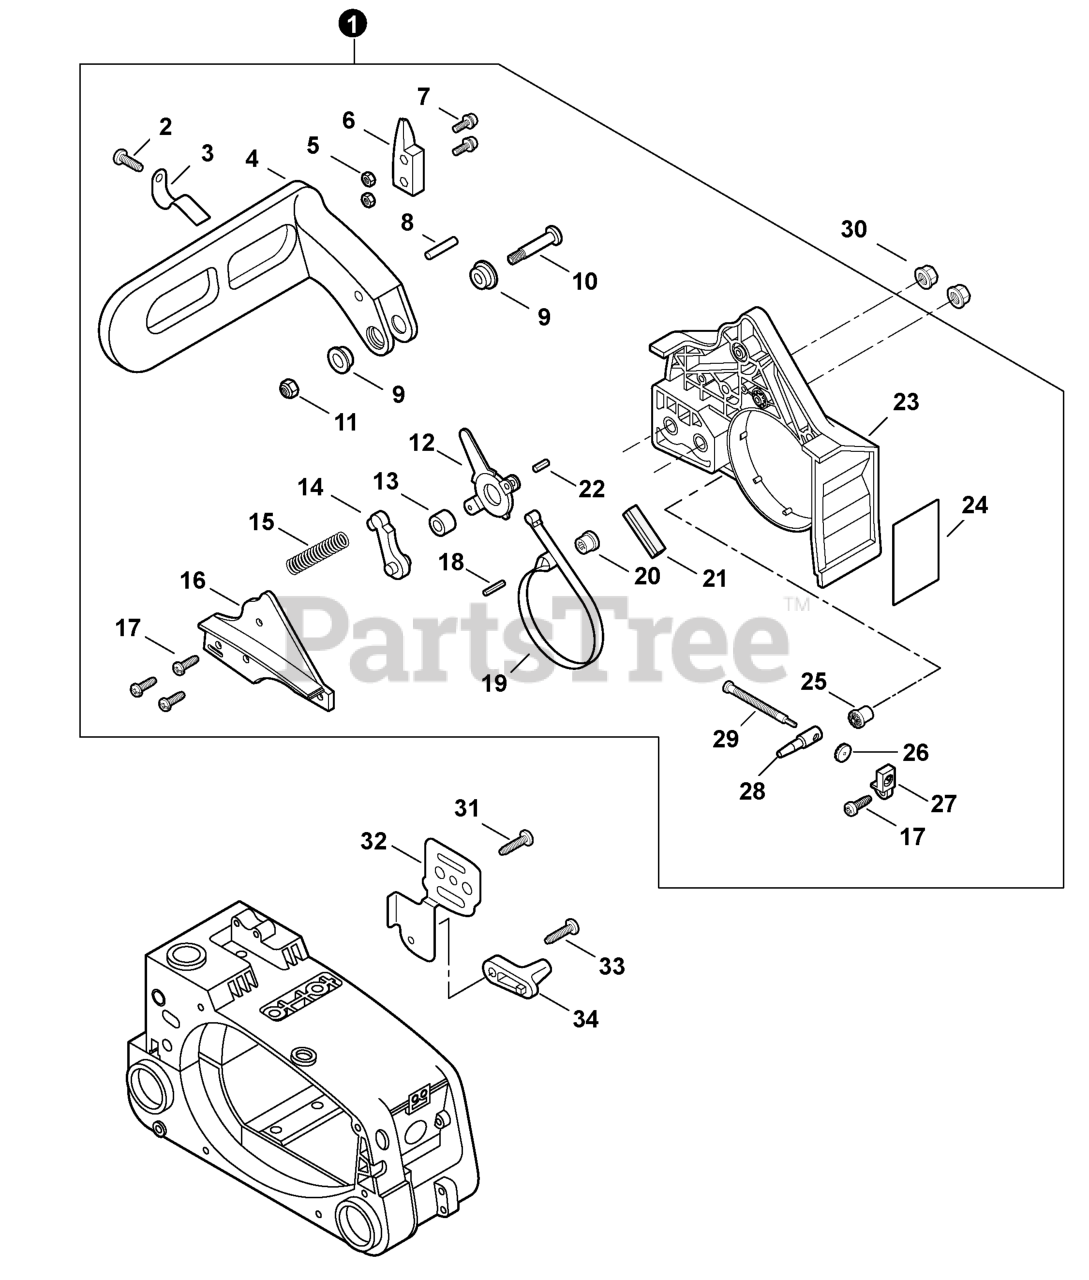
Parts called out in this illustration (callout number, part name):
1	BRAKE ASSY, CHAIN
2	SCREW 4x10
3	SPRING, FLAT
4	LEVER, BRAKE
6	WEIGHT, BRAKE
7	SCREW 4x20
8	ROLLER 4x23.8
9	COLLAR 5.3x10x13xL5
10	SCREW 5x32
11	NUT, LOCK M5
12	LEVER, BRAKE
13	SPACER 8x12x9
14	STOPPER, BRAKE
15	SPRING, COMPRESSION
16	COVER, BRAKE
17	SCREW 4x12
18	PIN, SPRING 2.5x12
19	BAND, BRAKE
20	ADJUSTER, BRAKE
21	SEAL, BRAKE
22	PIN, SPRING 4x8.8
23	GUARD, SPROCKET
24	SHIELD, HEAT 35x60x0.10
25	GEAR, BEVEL
26	GEAR, BEVEL
27	COLLAR 8
28	TENSIONER, CHAIN
30	NUT, FLANGE M6
31	SCREW 4x10
32	PLATE, GUIDE
33	SCREW, TAPPING 5x20
34	CATCHER, CHAIN
